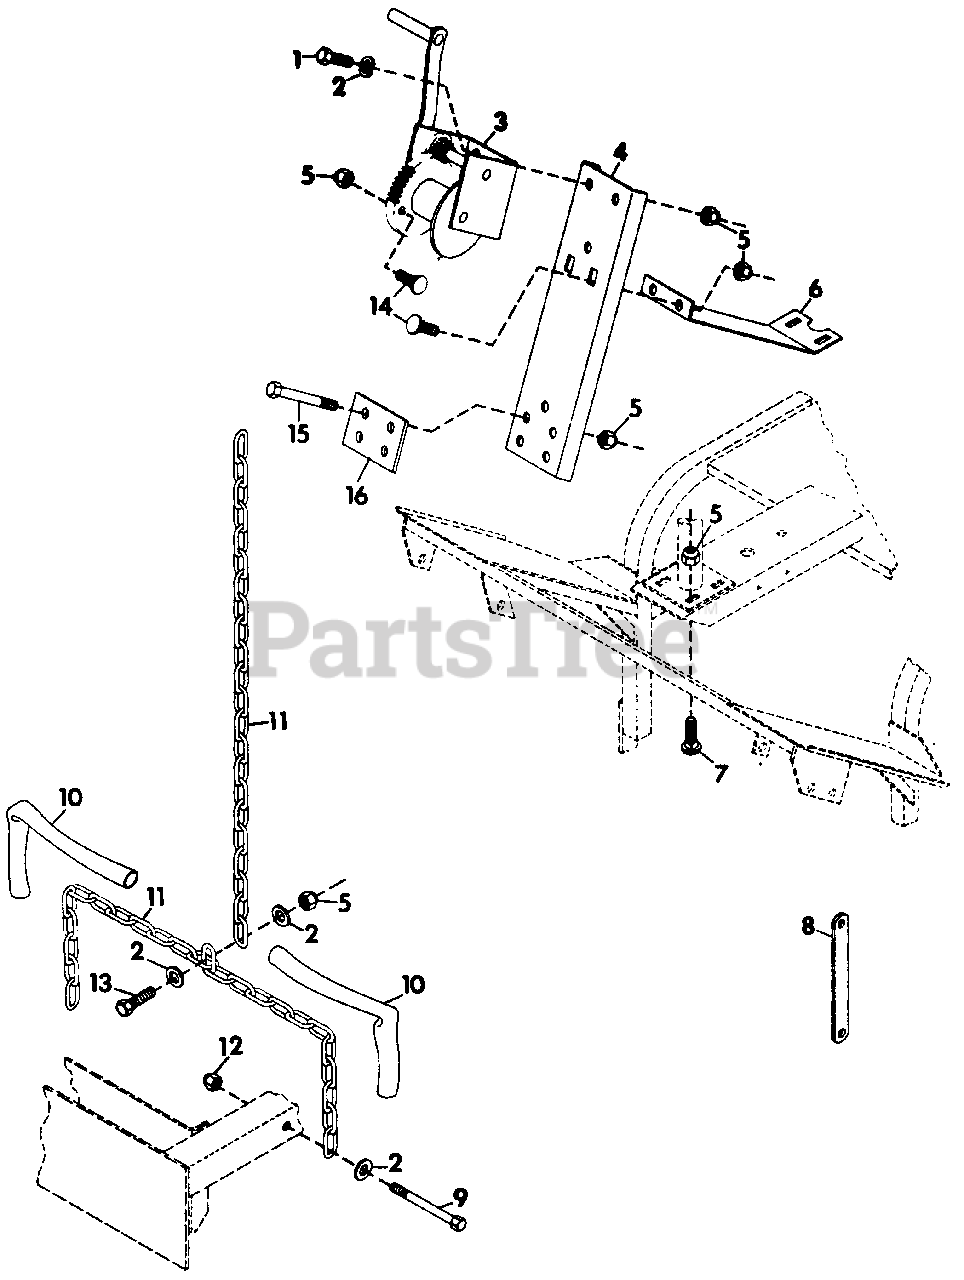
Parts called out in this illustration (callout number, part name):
1	BOLT, HEX 3/8-16X1
2	WASHER, FLAT .406X.812X.065
3	WINCH
4	CHANNEL, WINCH LIFT
5	NUT, LOCK 3/8-16
6	BRACE, WINCH CHANNEL
7	BOLT, 3/8-16X1.25 RD HD SQ NK
8	BAR, DECK LIFT
9	BOLT, HEX 5/16-24X2.75
10	TUBING
11	CHAIN, MOWER LIFT
12	NUT, LOCK 5/16-24
13	BOLT, HEX 3/8-16X1.125
14	BOLT, 3/8-16X.875 RD HD SQ NK
15	BOLT, HEX 3/8-16X2.5
16	PLATE, CHANNEL CLAMP
